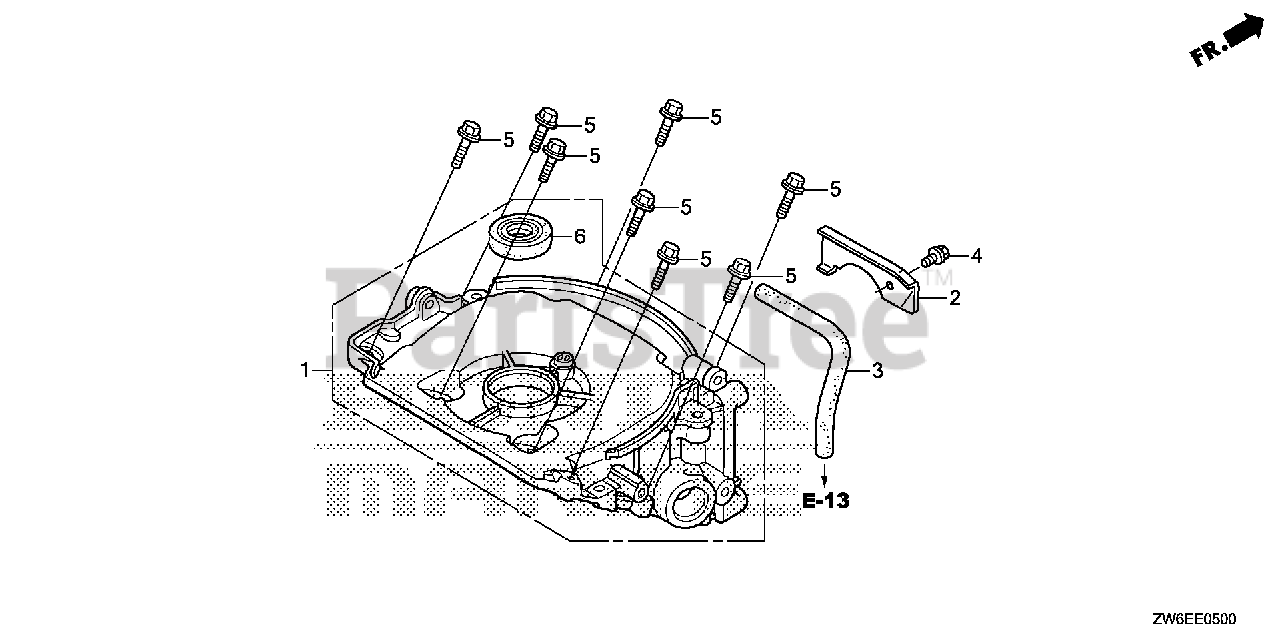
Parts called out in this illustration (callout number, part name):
1	CASE ASSY., OIL
2	PLATE, TUBE SETTING
3	TUBE, CLUTCH HOUSING BREATHER
4	BOLT, FLANGE (5X10) (CT200)
5	BOLT, FLANGE (5X23) (CT200)
6	OIL SEAL (17X27X5) (KOYO)
